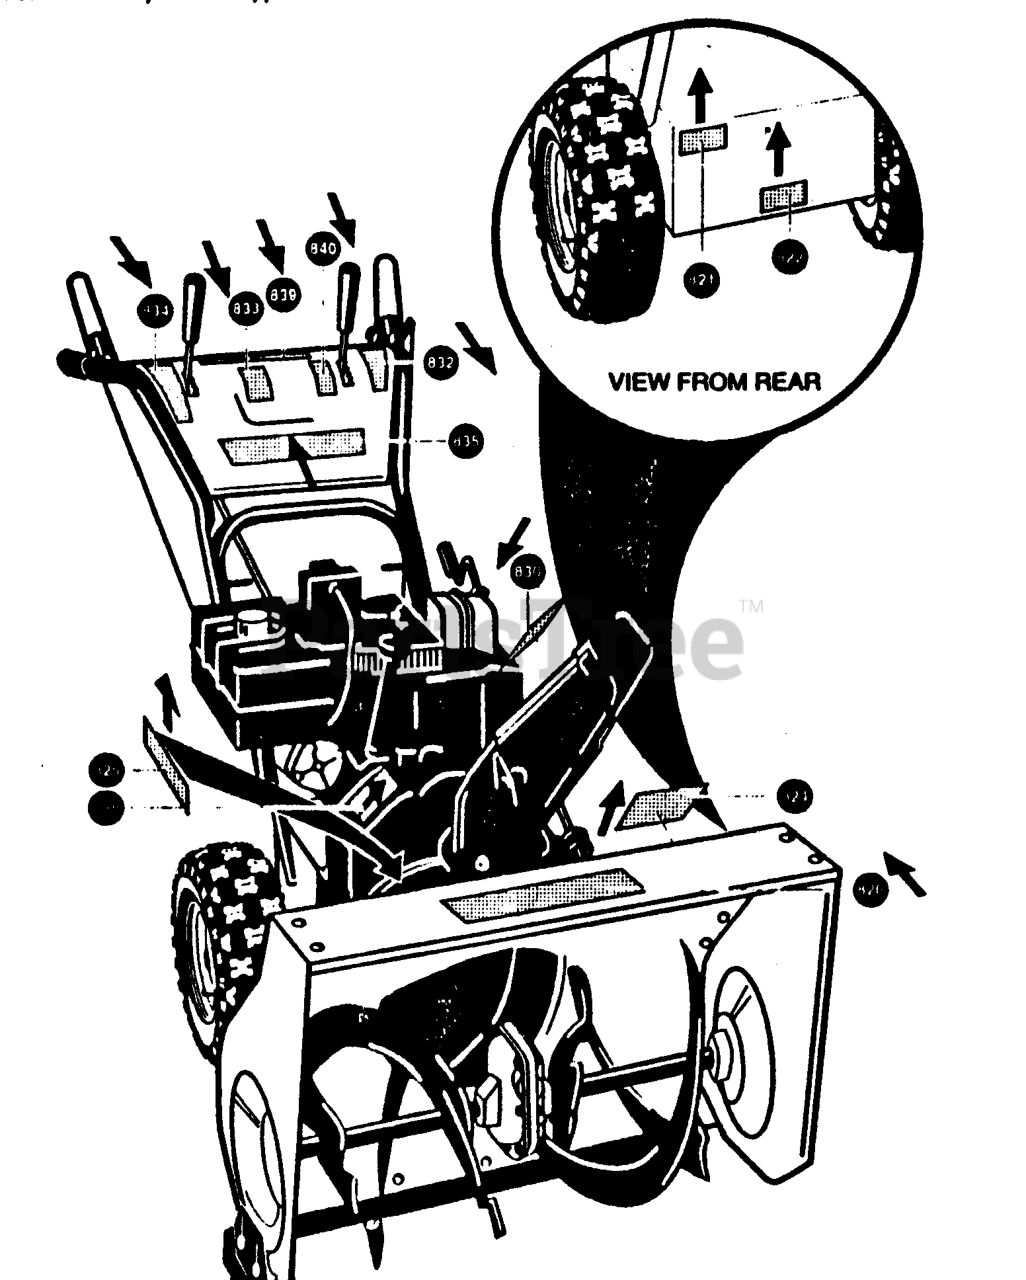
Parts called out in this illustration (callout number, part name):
821	NOT A SERVICABLE PART
822	DECAL-OVER ADJ OF DISC
824	DECAL-DANGER AUGER/FOOT
825	DECAL, DANGER
826	DECAL, HUSQ ST927E
830	DECAL, DANGER CHUTE
832	DECAL, TRACTION DRIVE
833	DECAL-SNOW CONDITIONS
834	DECAL, GEAR SELECTOR
835	DECAL, CONTROL PANEL
838	DECAL, BELT STRETCH & ADJ
839	DECAL, SINGLE HAND
840	DECAL-CHUTE CONTROL
